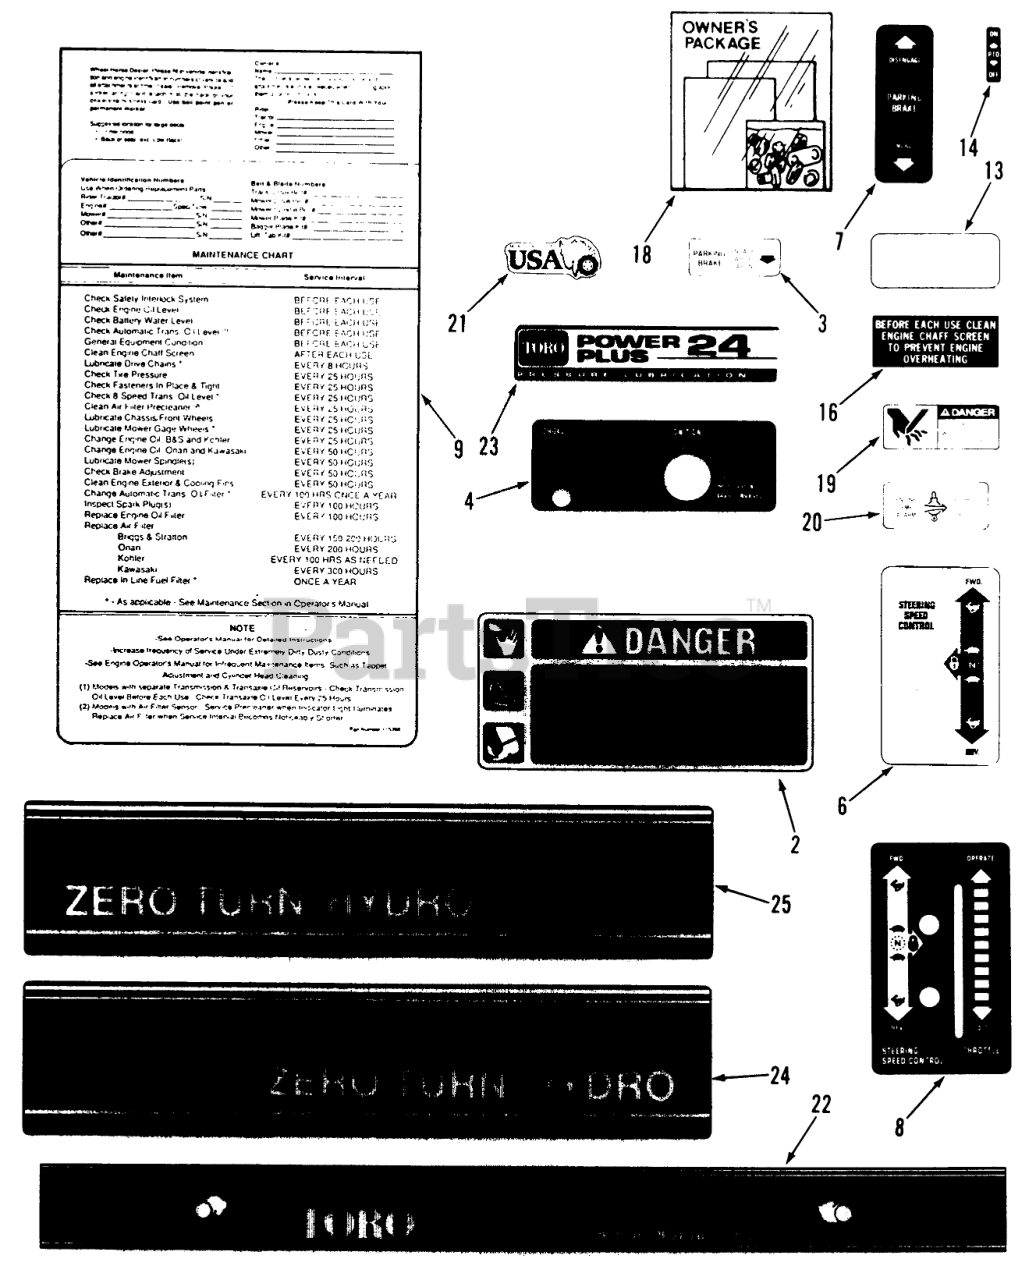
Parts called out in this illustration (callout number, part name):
2	DECAL-DANGER
3	Decal-Parking Brake
4	DECAL-CHOKE/IGNITION
6	Decal-SpeedControl
7	Decal-Parking Brake
8	DECAL-STRG THROTTLE
9	MAINTENANCE-DECAL
13	DECAL-OVERLAY
14	DECAL-PTO
16	DECAL-ENGINE SCREEN
18	Loose Parts Package-New Tractor
19	DECAL-DANGER
20	Decal-Temperature Alarm
21	DECAL-MADE IN USA BK
22	Decal-Hood
23	DECAL-PWR PLUS 24 PL
24	DECAL-ZERO TURN R.H.
25	DECAL-ZERO TURN L.H.
